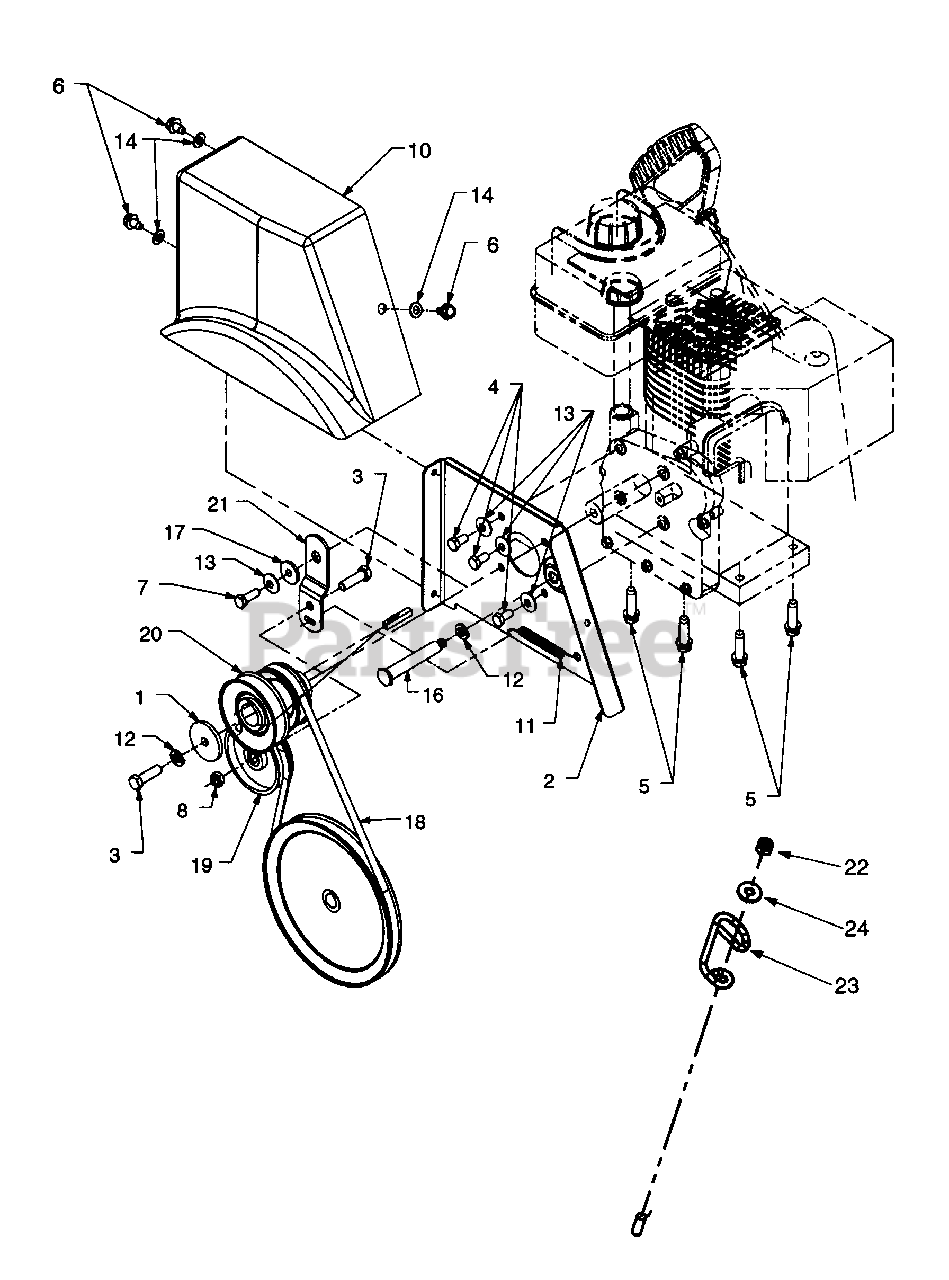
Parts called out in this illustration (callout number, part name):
1	Washer .390 I.D. x 1.75
2	Brkt Asm:Cvr:Belt
3	Hex Head Screw
4	Hex Hd. Screw 5/16-24 x .625
5	Hex TT-Tap Scr. 3/8-16 x 1.25" Lg.
6	Hex Wash. Screw 5/16-18
7	Hex Lock Screw 5/16-24x.875
8	Jam Nut 3/8-24 Thd.
10	Belt Cover
11	Spring: Extension
12	L-Wash. 3/8
13	Bell-Wash. .340 I.D. x .872 O.D.
14	Fl-Wash. .330 I.D. x .630 x .06
16	Shld. Screw .498 x 2.99 Lg.
17	Shld. Spacer
18	Variable Speed Belt
19	Fl-Idler Pulley 3.0" Dia.
20	Double Pulley
21	Idler: Brkt
22	Hex Lock Nut 1/4-20
23	Cable Control Wire
24	Fl-Wash. .28 x .74 x .063
